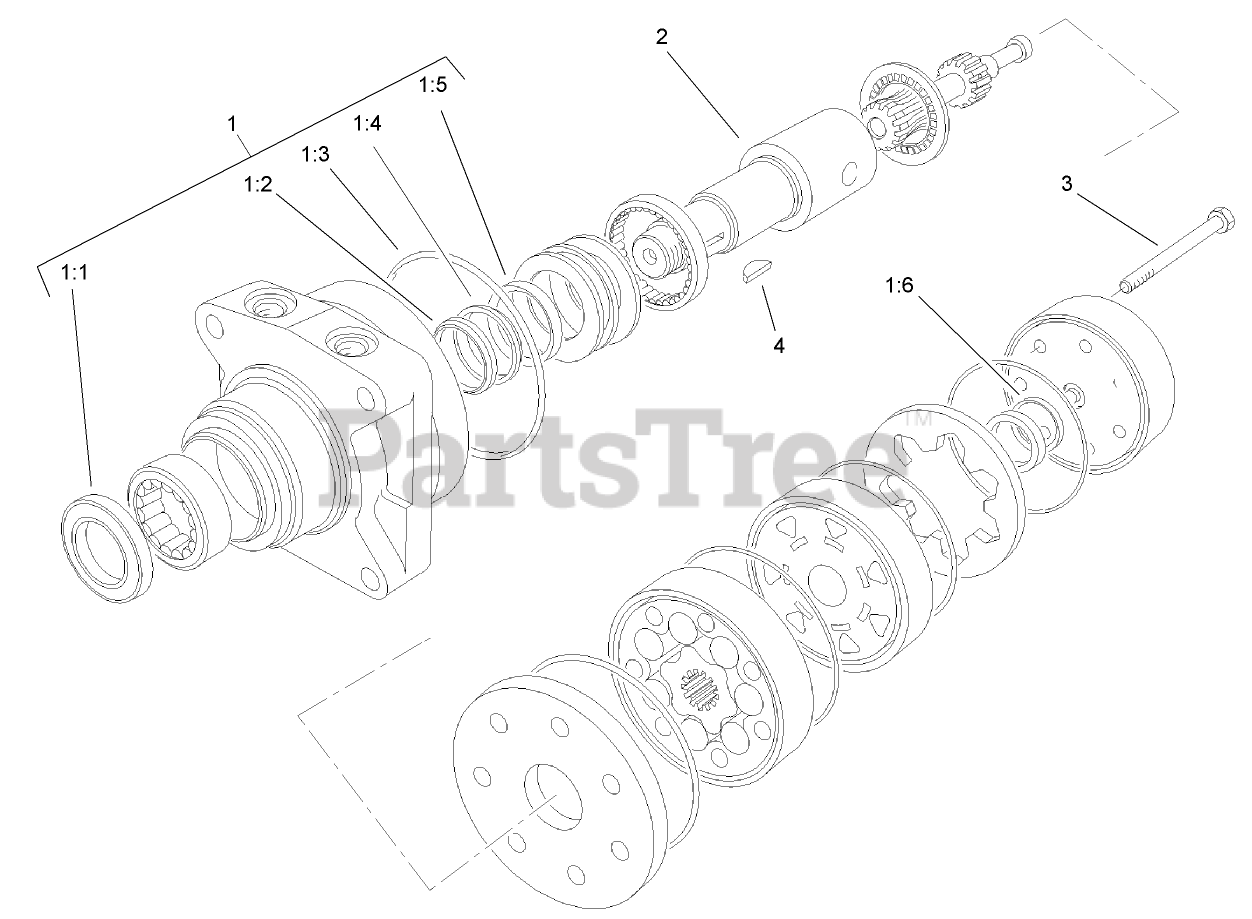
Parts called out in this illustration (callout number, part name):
1	SEAL KIT
1:1	SEAL-DIRT AND WATER
1:2	Washer-Backup
1:3	Seal-Ring
1:4	Washer-Backup
1:5	Seal-Inner
1:6	Seal-Commutator
2	SHAFT-COUPLING
3	SCREW-CAP, HH
4	KEY-WOODRUFF
